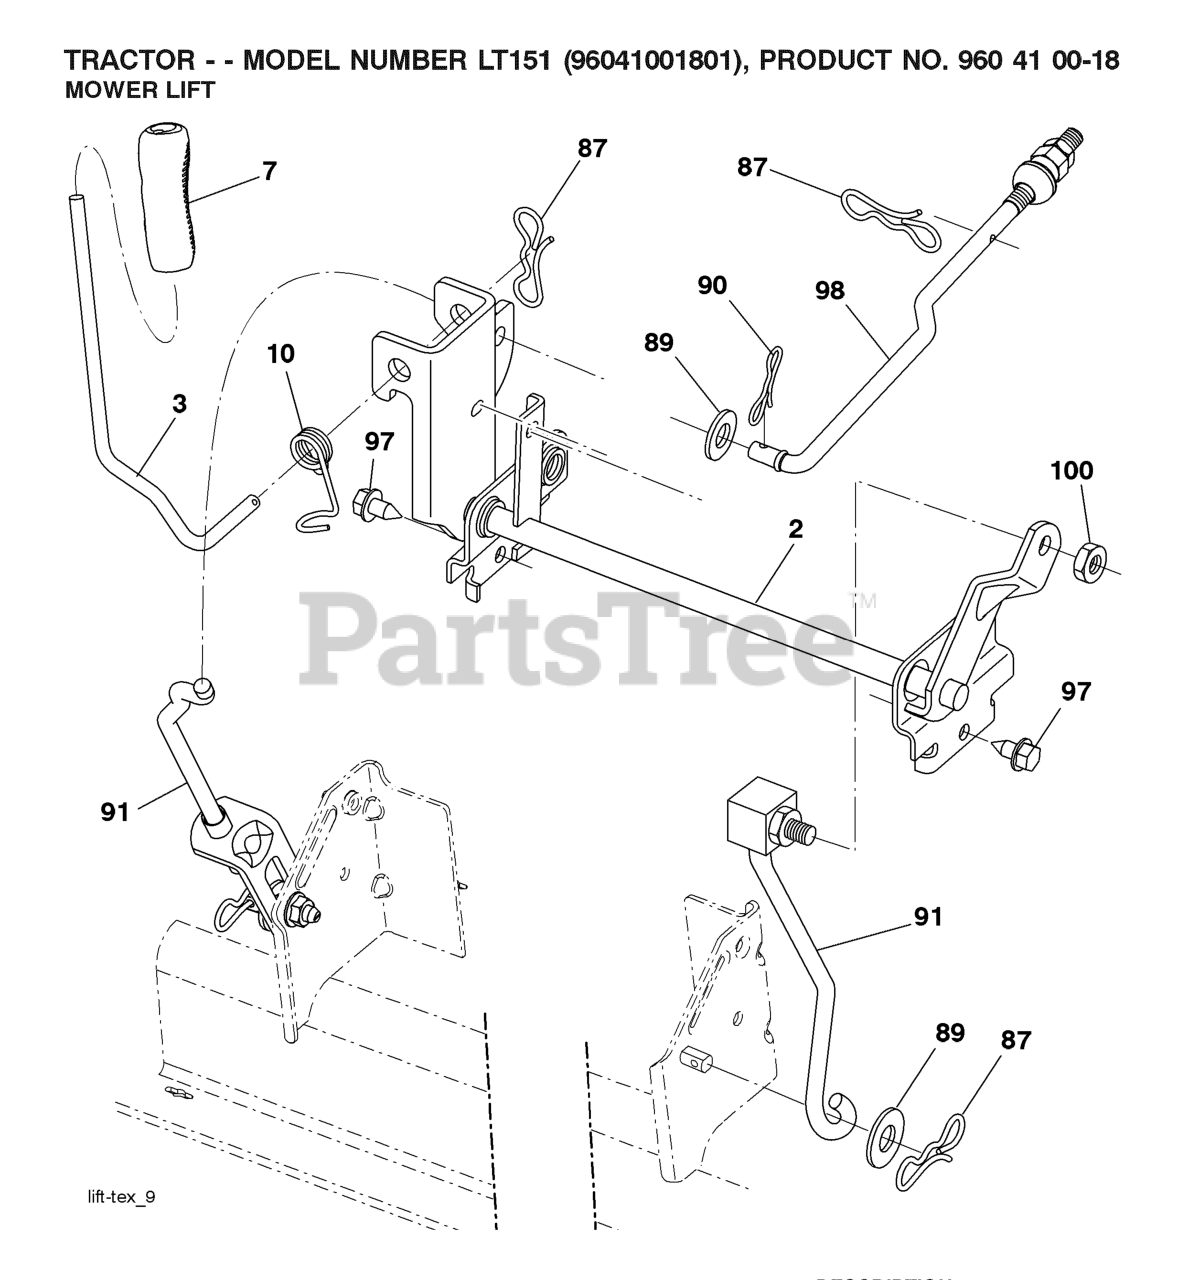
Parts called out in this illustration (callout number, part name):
2	SHAFT.ASM.LIFT.CROSS.H
3	LEVER.LIFT.HANDLE.LT
7	GRIP.LEVER.5625.ID
10	SPRING.TORSION.LIFT.HANDLE
87	PIN.COTTER.7/16.BOW TI.
89	WASHER.CLEAR.ZINC
90	PIN.COTTER.5/16.BOW TI
91	LIFT LINK SUSP. MOWER REAR
97	SCREW 3/8-16X3/4
98	LINK.ASM.SUSP.FRONT.MW
100	LOCKNUT
